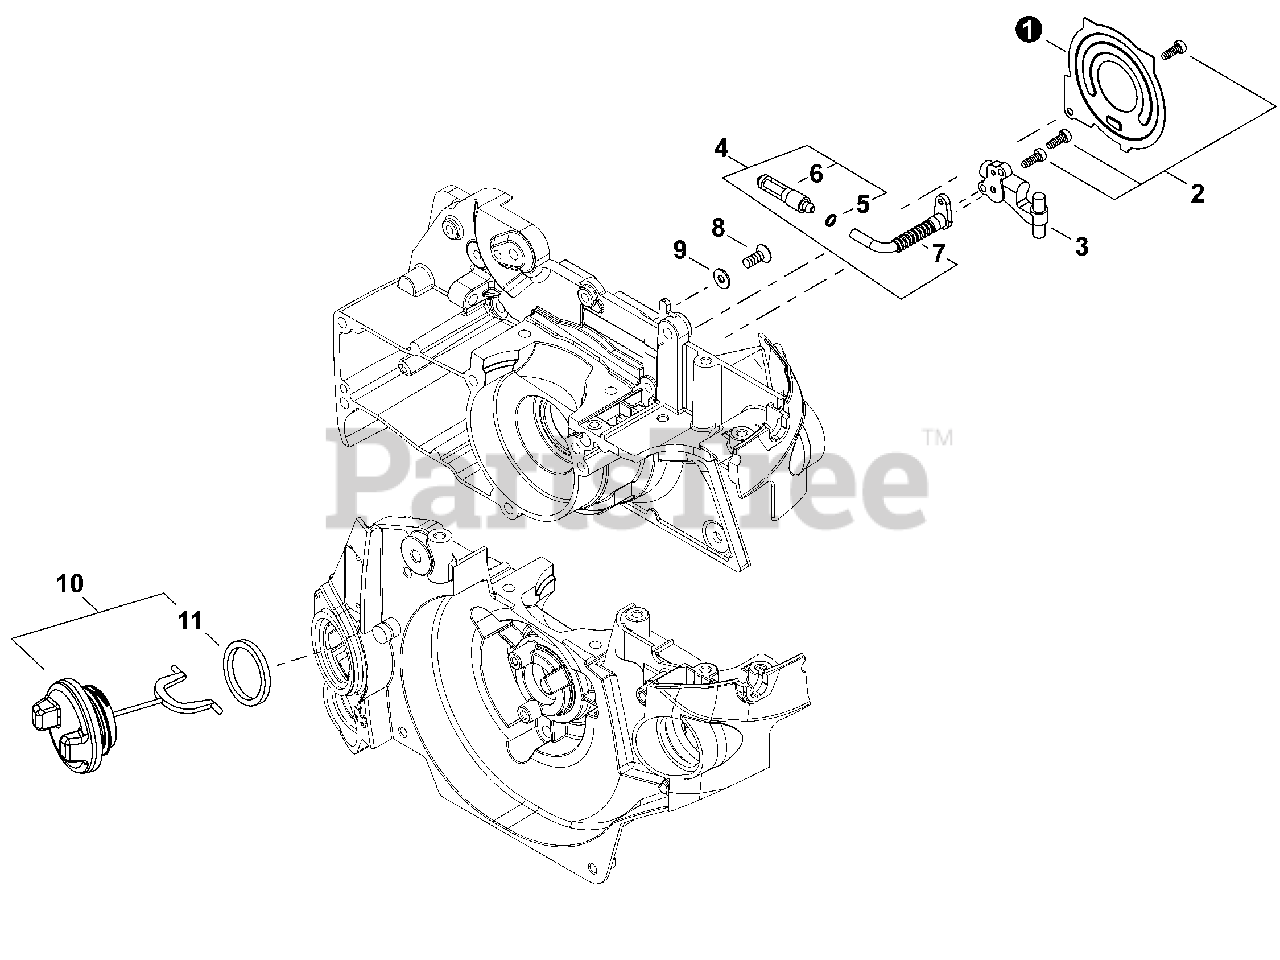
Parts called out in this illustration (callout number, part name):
1	COVER, OILER
2	BOLT, ADHESIVE M4×14
3	OIL PUMP ASSY
4	FILTER, OIL ASSY
5	CLIP Ø6
6	FILTER, OIL
7	PIPE, OIL
8	SCREW 4×8
9	WASHER 4mm
10	CAP ASSY, OIL
11	GASKET, CAP
